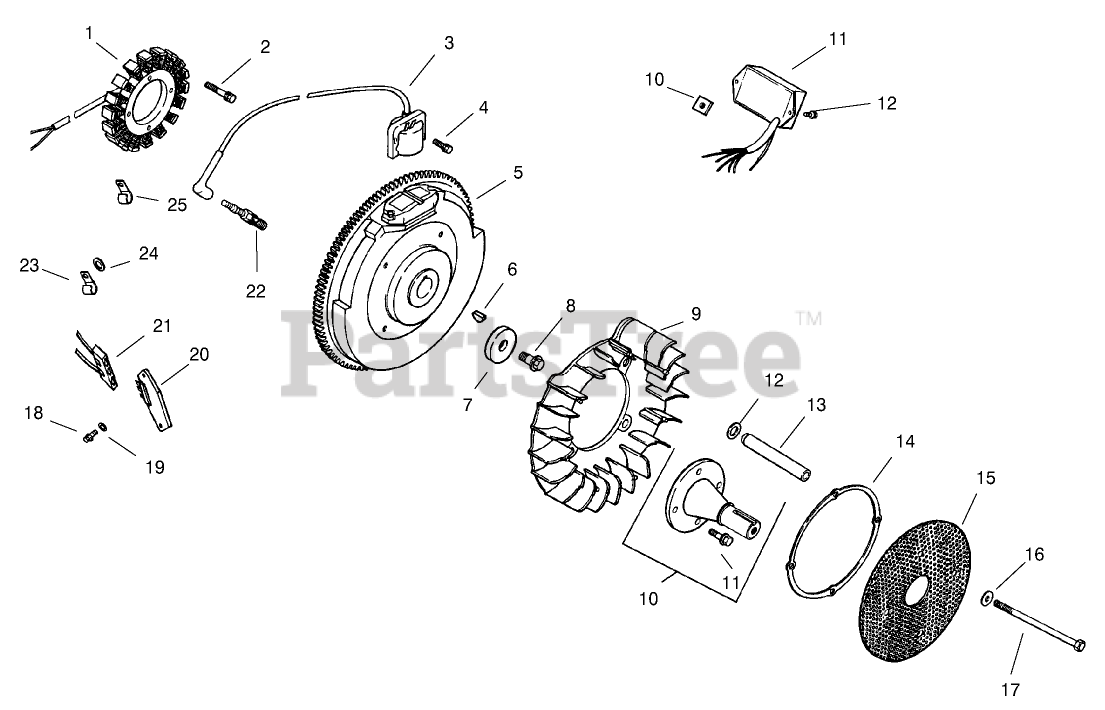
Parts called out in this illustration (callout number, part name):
1	Kit, 15 amp stator (Incl. 24 126 71 bracket)
2	Screw
3	Module-Ignition
4	Screw
5	Flywheel
6	Key
7	Washer
8	Screw
9	Fan
10	Kit, front drive shaft (Includes 14)
11	Screw
12	Washer, sping
13	Spacer
14	Ring-Support
15	Screen-Grass
16	Washer
17	Screw-Hex
18	Screw
19	Washer
20	Rectifier-Regulator
21	Connector
22	Plug-Spark
23	Clip
24	Washer
25	Clip
